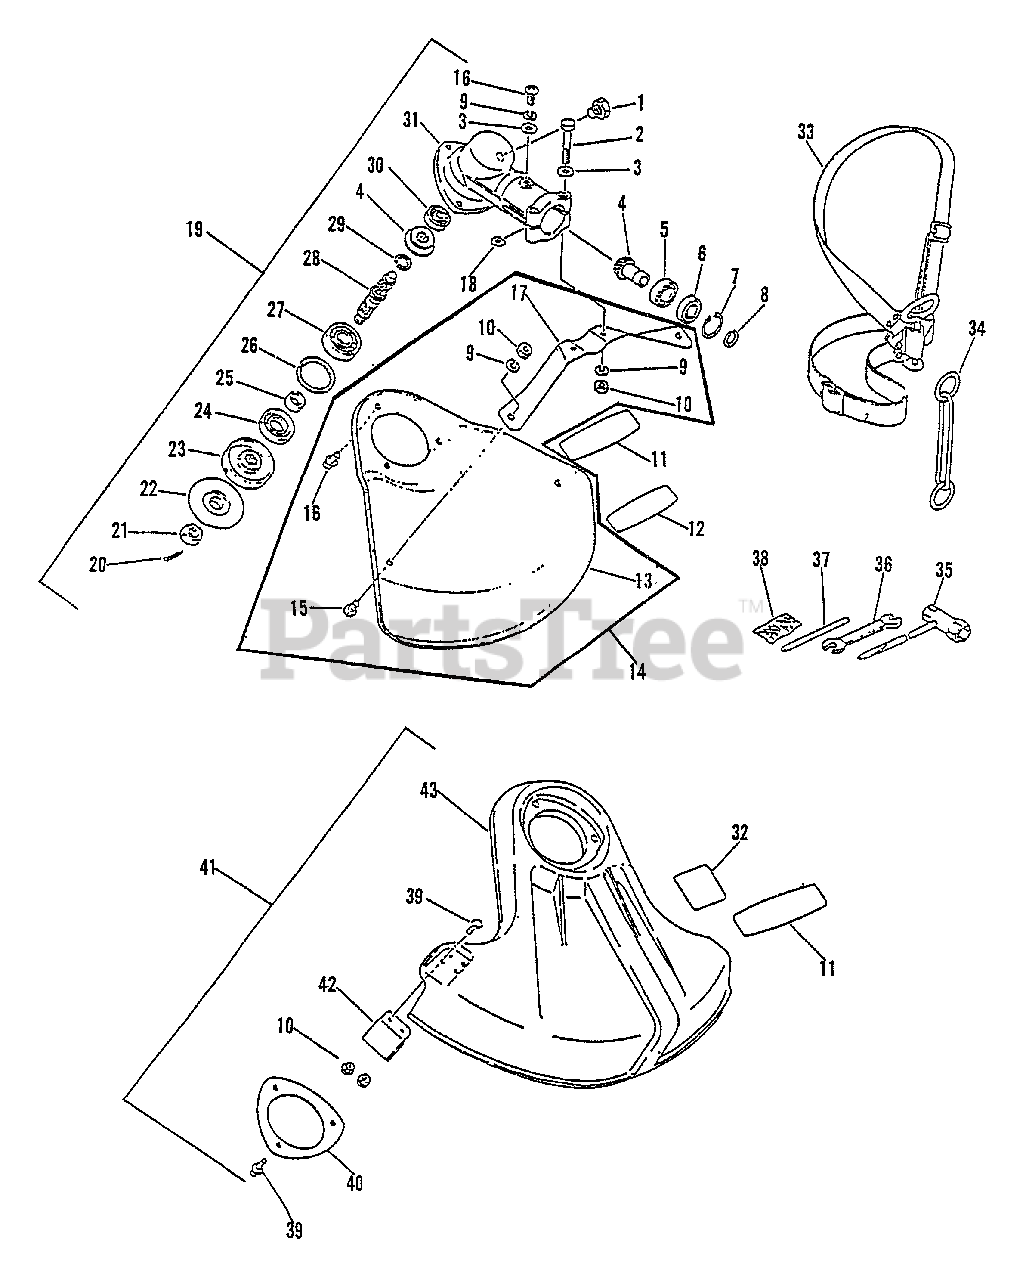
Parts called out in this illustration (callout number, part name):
1	BOLT - 8X8
2	BOLT - 5X35
3	WASHER - 5
4	GEAR SET - BEVEL
5	BEARING, BALL - 6900
6	BEARING, BALL - 6900Z
7	RING, RETAINING - 22
8	RING, RETAINING - 12
9	LOCKWASHER - 5
11	LABEL - LESCO
12	LABEL - CAUTION
13	SHIELD, DEBRIS - METAL
14	DEBRIS SHIELD KIT - METAL
15	SCREW - 5X8
16	SCREW - 5X10
17	BRACKET, SHIELD
19	GEAR CASE ASSY
20	PIN, SPLIT - 2X22
21	NUT - 10 -- LEFT HAND
22	ADAPTOR, BLADE - LOWER
23	ADAPTOR, BLADE - UPPER
24	SEAL, OIL
26	RING, RETAINING - 32
27	BEARING, BALL - 6201
28	GEAR - SHAFT
29	RING, RETAINING - 10
30	BEARING, BALL - 609
31	CASE, GEAR
32	LABEL - CAUTION
33	SHOULDER STRAP ASSY
35	T-WRENCH - 17X19mm
36	SPANNER - 8X10mm
37	LOCKING TOOL
38	PIN, SPLIT - 2X22
39	SCREW - 5X16
40	PLATE, SHIELD
41	DEBRIS SHIELD KIT
42	KNIFE, TRIMMER LINE
43	SHIELD, DEBRIS - PLASTIC
